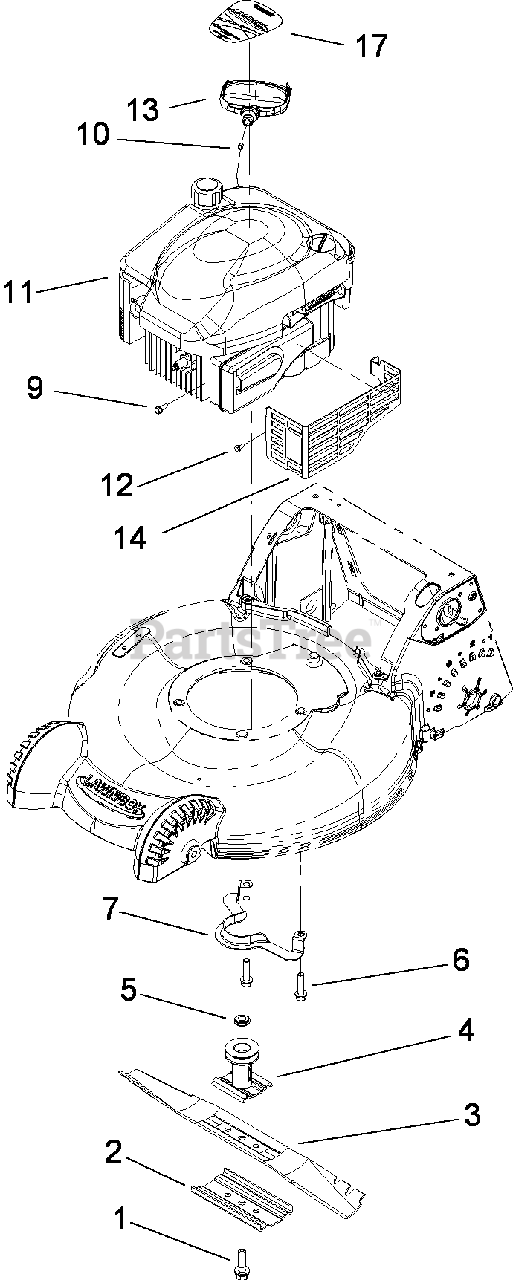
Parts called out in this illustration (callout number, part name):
1	BOLT-BLADE
2	SUPPORT-BLADE
3	BLADE-21 INCH
4	BLADE DRIVER ASM
5	Spacer-Driver
6	SCREW-HWH
9	SCREW-HWH
10	STOP-ROPE
12	SCREW-TAPTITE
13	HANDLE-RECOIL
14	SHIELD-MUFFLER
17	DECAL-ENGINE
